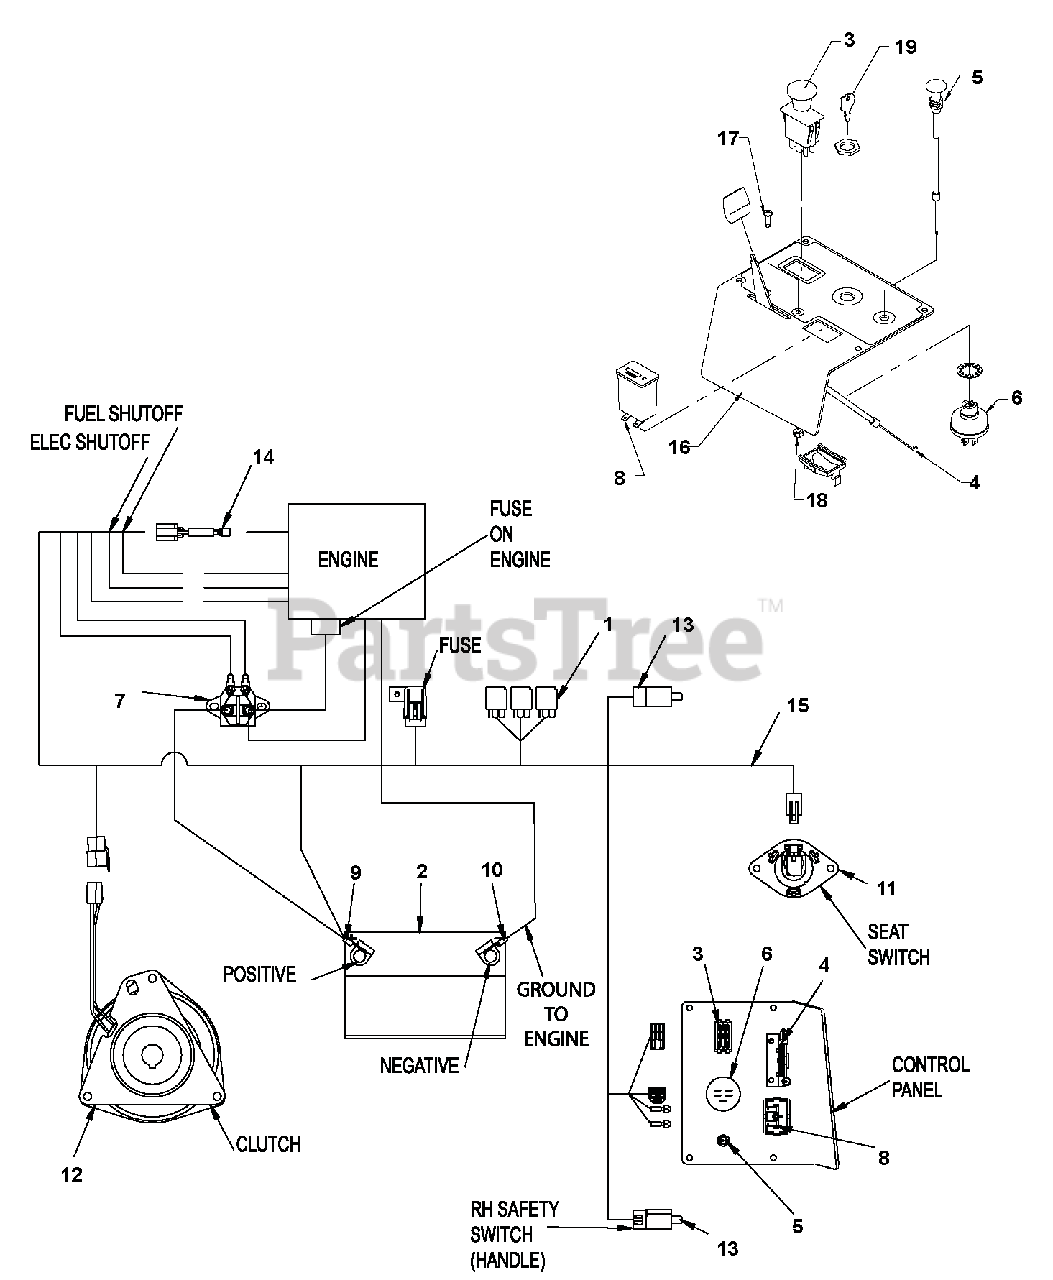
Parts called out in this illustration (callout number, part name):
1	RELAY, ISO MINI ELEC.
2	BATTERY, 12V-U1-CCA270MIN
3	SWITCH, PTO ENGAGEMENT
4	CABLE, THROTTLE
5	CABLE, CHOKE 48.0"
6	PLATE, ENGINE MOUNTING
7	SOLENOID
8	HOUR METER - DIGITAL
9	STARTER CABLE
10	CABLE, BATTERY - 35" GROUND
11	SEAT SWITCH S/O
12	CLUTCH, ELECT - OGURA GT, 2.5
13	SWITCH, PLUNGER DP -N.O.-N.C.
14	ADAPTER HARNESS, 19KAI/23KAW
15	HARNESS, POWER UNIT WIRE
16	SCR-MCH 10-24X.62 P/HD
17	SCREW, 10-24X.625 PAN PHL MACY
18	LOCKNUT, 10-24 CENTER Y
19	KEY-IGN SERVICE ONLY
